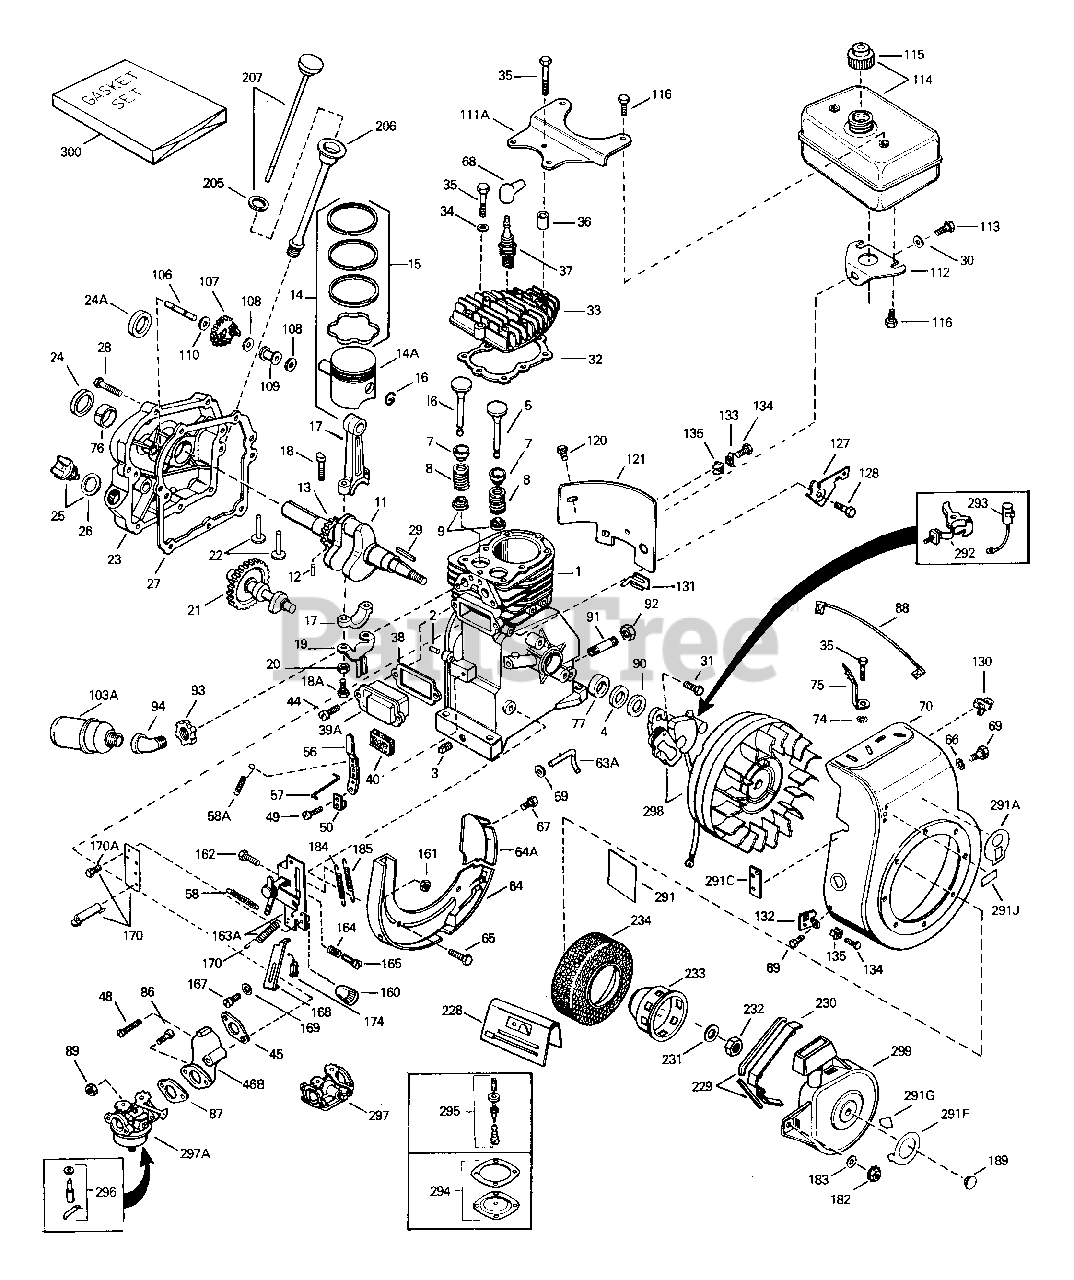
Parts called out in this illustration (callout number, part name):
1	"Cylinder Assy. (2-1/2" Bore)
2	Pin, Dowel
3	Plug, Oil drain (Square hd.) (1/4-18)
4	Seal, Oil
5	Valve, Intake (Standard)
5	Valve, Intake (1/32" oversize)
6	Valve, Exhaust (Standard)
6	Valve, Exhaust (1/32" oversize)
7	Cap, Upper valve spring
8	Spring, Valve
9	Cap, Lower valve spring
11	Crankshaft Assy.
12	Pin, Crankshaft gear
13	Gear, Crankshaft
14	Piston, Pin & Ring Assy. (Std.) (2-1/ 2")
14	Piston, Pin & Ring Assy. (.010 oversi ze)
14	Piston, Pin & Ring Assy. (.020 oversi ze)
14A	Piston & Pin Assy. (Std.)
14A	Piston & Pin Assy. (.010 oversize)
14A	Piston & Pin Assy. (.020 oversize)
15	Ring Set, Piston (Standard) (2-1/2")
15	Ring Set, Piston (.010 oversize)
15	Ring Set, Piston (.020 oversize)
16	Ring, Piston pin retaining
17	Rod Assy., Connecting
18	Bolt, Connecting rod
18A	Bolt, Connecting rod
19	Dipper, Oil
20	Nut, Connecting rod bolt
21	Camshaft (Compression Release)
22	Lifter, Valve
23	Cover, Cylinder
24	Seal, Oil (1-3/8" Diameter)
24	Seal, Oil (1-1/2" Diameter, 1/4" thic kness)
24	Seal, Oil (1-5/8" Diameter)
24	Seal, Oil (1-1/4" Diameter, 3/16" thi ckness)
24	Seal, Oil (1-1/4" Diameter, 1/4" thic kness)
25	Plug, Oil filler
26	Gasket, Oil filler
27	Gasket, Cylinder cover
28	Screw, Hex hd. Sems, 1/4-20 x 1
28	Screw, Hex hd. Sems, 1/4-20 x 1-1/4
29	Key, Flywheel
30	Washer, Flat
31	Screw, Hex hd. Sems, 1/4-20 x 5/8
31	Screw, Hex washer hd. Sems, 1/4-20 x 1-1/8
32	Gasket, Cylinder head
33	Head, Cylinder
35	Screw, Hex flange hd., 5/16-18 x 1-1/ 2
35	Screw, Hex hd., 5/16-18 x 2-3/8
35	Screw, Hex flange hd., 5/16-18 x 2
35	Screw, Hex flange hd., 5/16-18 x 2-1/ 4
35	Screw, Special Hex hd. tapped, 5/16-1 8 x 2
37	Plug, Spark
37	Resistor Spark Plug
38	Gasket, Breather
39A	Breather Assy.
40	Element, Breather
44	Screw, Fil. hd. Sems, 10-24 x 1/2
45	Gasket, Intake pipe (1/32" thick)
46B	Pipe, Intake
48	Screw, Fil. hd. Sems, 1/4-20 x 1-3/8
48	Screw, Hex hd. Sems, 1/4-20 x 1
48	Screw, Phil. Fil. hd. Sems, 1/4-20 x 1-19/32
48	Screw, Fil. hd. Sems, 1/4-20 x 1-7/32
49	Screw, Hex washer hd., 8-32 x 5/16
56	Lever, Governor
57	Link, Throttle
58	Spring, Extension
59	Washer, Flat
63A	Rod, Governor
64	Baffle, Blower housing
64A	Extension, Baffle
65	Screw, Hex washer hd. durlock, 1/4-20 x 5/8
66	Flatwasher
67	Screw, Hex washer hd. shakeproof
68	Cover, Spark plug
69	Screw, Hex hd. Sems, 1/4-28 x 7/16
70	Housing, Blower (5.56 dia. starter mt g. bolt
74	Lockwasher, 5/16
75	Clip, Shorting
76	Bushing, Crankshaft
77	Bushing, Crankshaft
86	Screw, Hex hd., 1/4-28 x 7/8
87	Gasket, Carburetor (1/32" thick)
88	Wire, Ground (Female fittings both en ds)
89	Nut & Lockwasher; 1/4-28
90	Gasket, Stator
106	Shaft, Mechanical governor
107	Gear Assy., Governor
108	Ring, Retaining
109	Spool, Governor
110	Washer, Flat
111A	Bracket, Upper fuel tank
113	Screw, Hex washer hd. Durlok, 1/4-20 x 5/8
114	Tank Assy., Fuel (Black Poly) (2 qt. )
115	Cap, Fuel filler (Red Plastic) (Spurt
115	Cap, Fuel filler (White Plastic) (Sta ndard)
116	Screw, Hex washer hd. thread cutting, 1/4-15
120	Screw, Fil. hd. Sems, 10-24 x 1/2
121	Extension, Blower housing
127	Bracket, Holddown
128	Screw, Hex washer hd. self-tap Sems, 10-24 x
134	Screw, Pan hd. self-tap, 8-18 x 3/8
135	Grommet
161	Locknut, 8-32
162	Screw, Hex washer hd. self-tap, Sems, 10-24
162	Screw, Fil. hd. Sems, 8-32 x 1/2
162	Screw, Fil. hd. Sems, 8-32 x 3/8
164	Spring, Compression
165	Screw, Fil. hd., 5-40 x 7/16
167	Screw, Hex washer hd. Sems, 10-32 x 3 /8
174	Terminal Assy.
182	Rivet, Pop
182	Nut & Lockwasher, 1/4-28
184	Spring, Extension
185	Spring, Extension
231	Washer, Belleville
232	Nut, Flywheel
233	Cup, Starter
234	Screen, Starter cup
291	Decal, Instruction
291A	Decal, Name
292	Contact Assy., Breaker
293	Condenser
296	Inlet Needle, Seat & Clip Assy.
297A	Carburetor
298	Magneto, Tecumseh
299	Starter, Rewind
300	* Gasket Set (Incl. items marked *)
